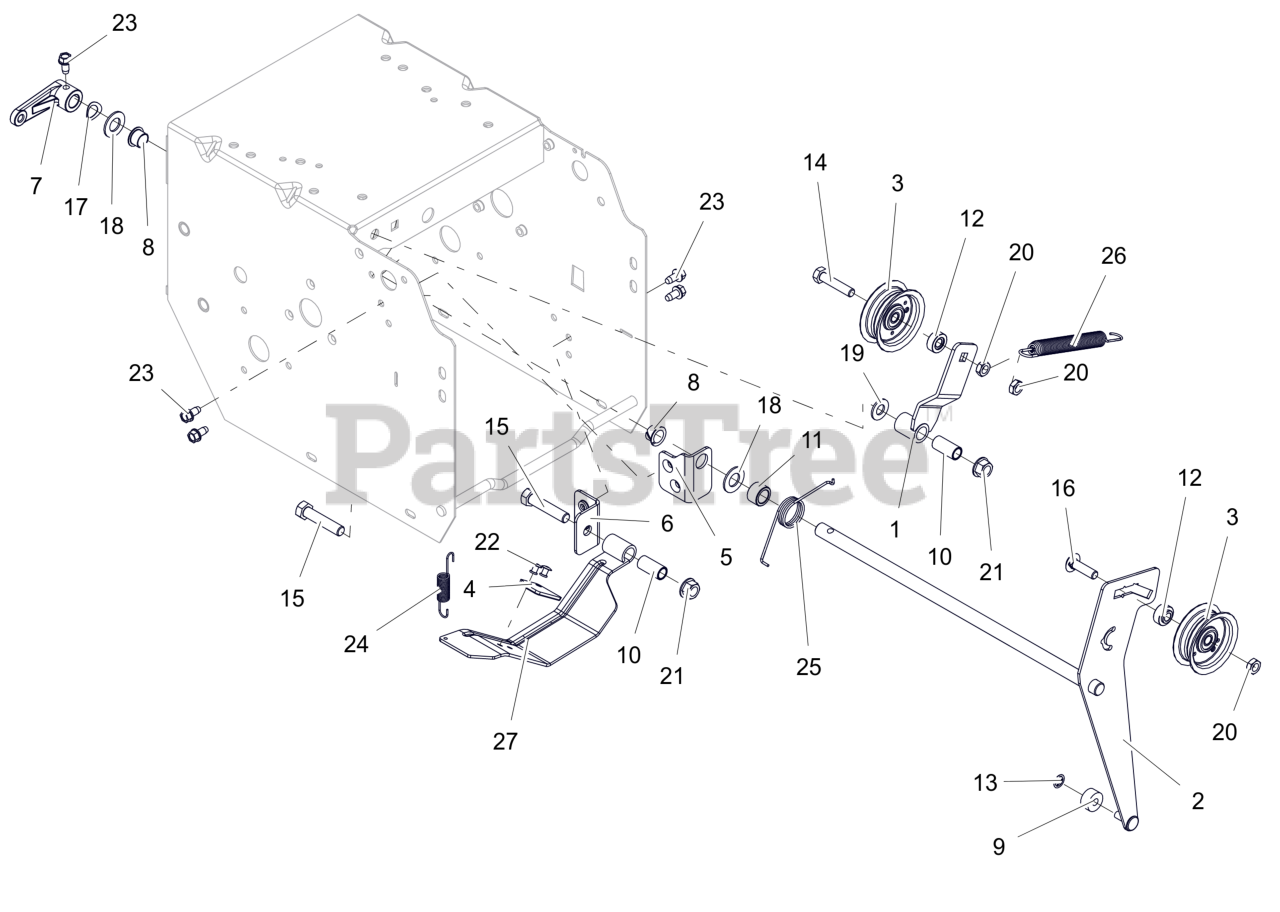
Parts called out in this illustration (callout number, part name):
1	WELDMENT, TRACTION IDLER ARM
2	WELDMENT- ATTACHMENT IDLER ARM
3	IDLER, FLAT - 2.00"
4	PAD, BRAKE
5	BRACKET, MOUNT - IDLER ARM
6	BRACKET, MOUNT - BRAKE
7	ARM, CLUTCH - ATTACHMENT
8	BUSHING, POLYLINER-.50 SPLIT
9	BSHG,SLV .265 X .625 X .375
10	BSHG-SLV .385X.500X1.045
11	BSHG-SLV .510X.751X.475
12	SPCR, BRG .315X.500X.358X.281
13	RG-RTNG-EXT .250X.010
14	BLT, HEX .31-18X1.50 G5 ZCC
15	BLT, HEX .38-16X1.75 G5 ZCC
16	BLT, RHSSN .31-18X1.125 G5 ZCC
17	WSHR-WAVE .50X.75X.015 .13FRHT
18	WSHR, FLT .531X1.00X.063 ZCC
19	WSHR,FLT .406X.812X.065 ZCC
20	NUT-LK-CTR-JAM .312-18 GB ZCC
21	NUT-LK-TOP-FLG .38-16 ZC120
22	RVT, POP .1875 ZCC
23	SCR-TAP .25-20X.50 HWH ZCC
24	SPRING-EXT .437 X .438 X 2.64
25	SG-TORS .075 X .955
26	SPRING, SWIVEL HOOK EXTENSION
27	BRAKE ARM W/PAD
